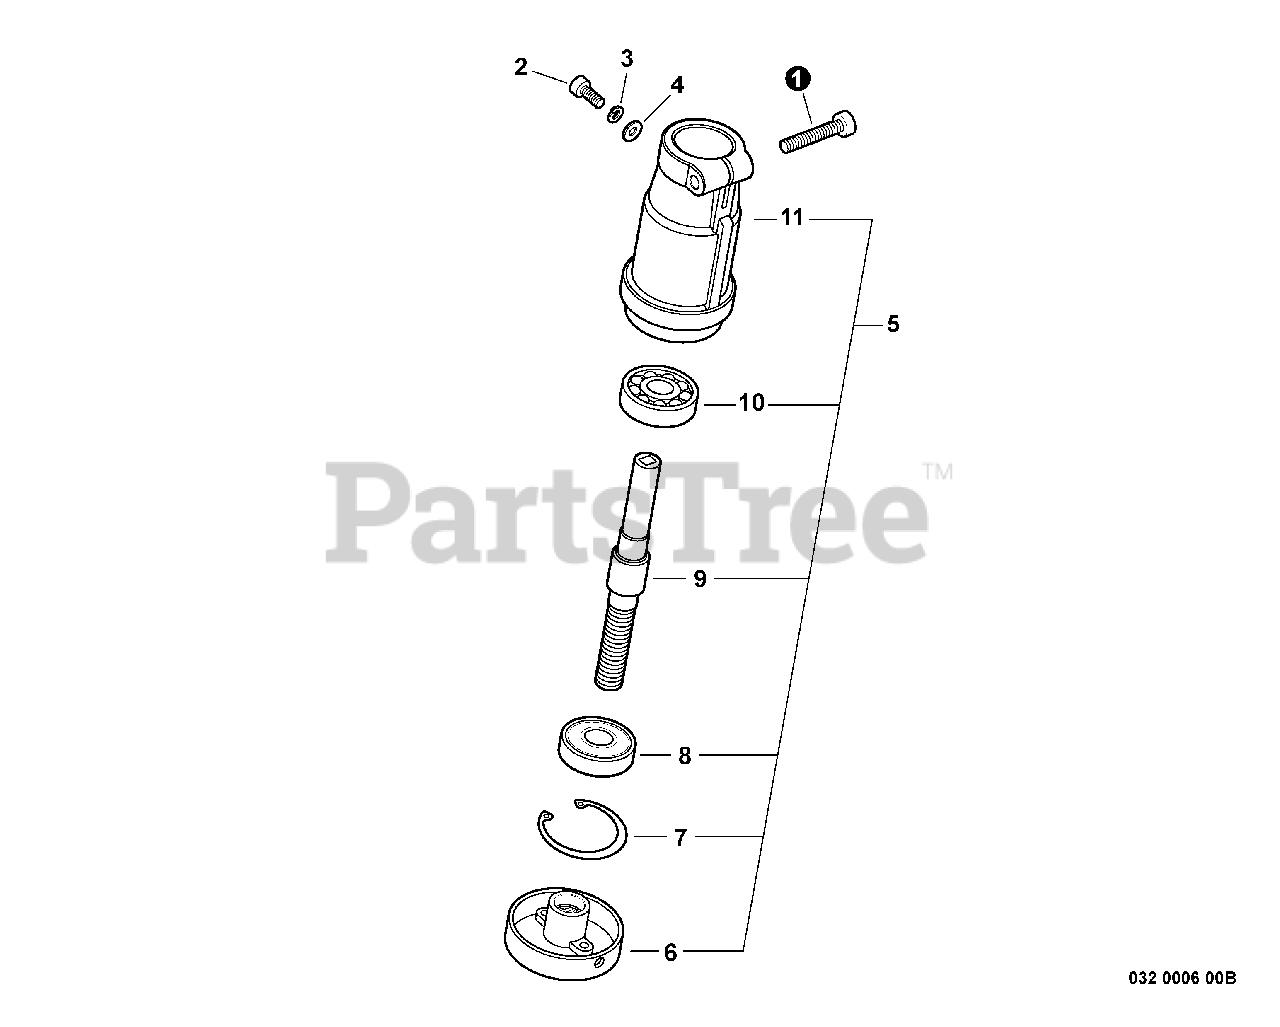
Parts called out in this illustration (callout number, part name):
1	SCREW - 5X25
2	SCREW - 4X10
3	LOCKWASHER - 4
4	WASHER - 4
5	GEAR CASE ASSY
6	ADAPTOR, BLADE - UPPER
7	RING, RETAINING - 30
8	BEARING, BALL - 6200
9	GEAR - SHAFT
10	BEARING, BALL - 6200
11	CASE, GEAR
